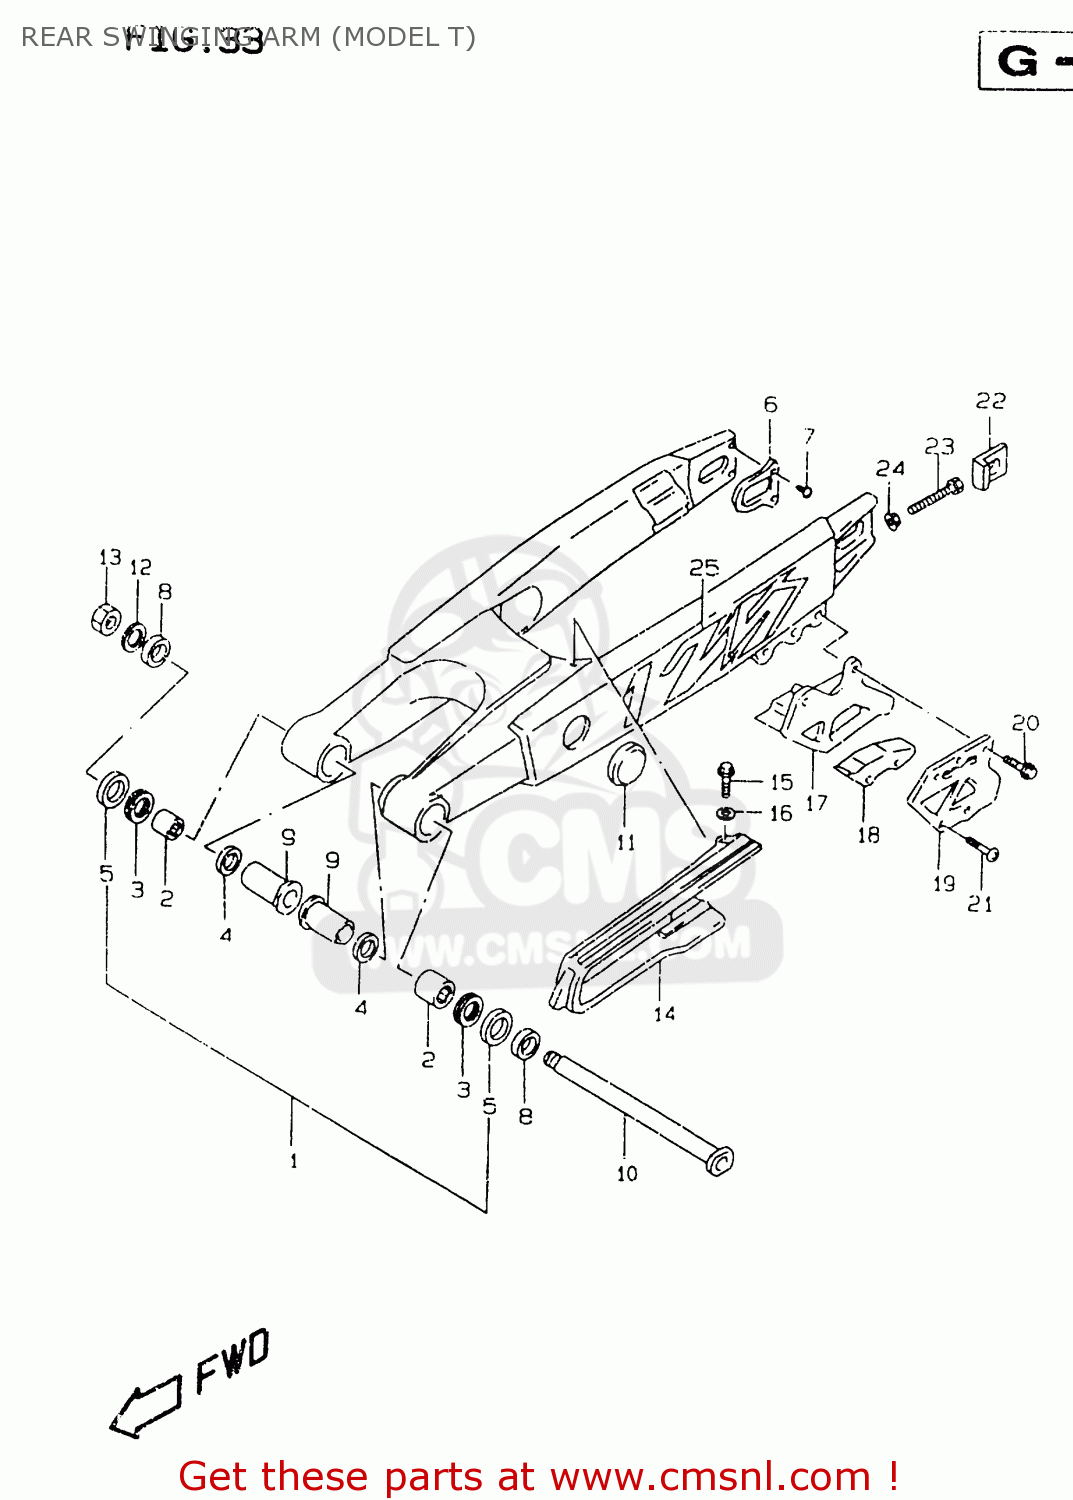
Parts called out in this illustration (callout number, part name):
1	SWING ARM ASSEMBLY,REAR
2	BEARING(22X29X30)
3	BEARING(22X35X2)
4	SEAL,OIL(22X29X4)
5	SEAL,RR SWGARM PIVOT OUTER
6	PLATE,SWING ARM,REAR
7	SCREW(5X8)
8	SPACER,RR SWGARM PIVOT OUTER
9	SPACER,SWGARM PIVOT INNER
10	SHAFT,RR SWINGINGARM PIVOT
11	CAP(OD:45)
12	WASHER, FIXED DRIVE FACE
13	NUT
14	BUFFER,CHAIN TOUCH DEFENSE
15	BOLT
16	WASHER
17	GUIDE,CHAIN
18	DEFENSE,CHAIN GUIDE
19	PLATE,CHAIN GUIDE OUTER
20	SCREW
21	SCREW(6X40)
22	WASHER,CHAIN ADJUSTER
23	BOLT(8X50)
24	NUT
25	EMBLEM,SWING ARM
